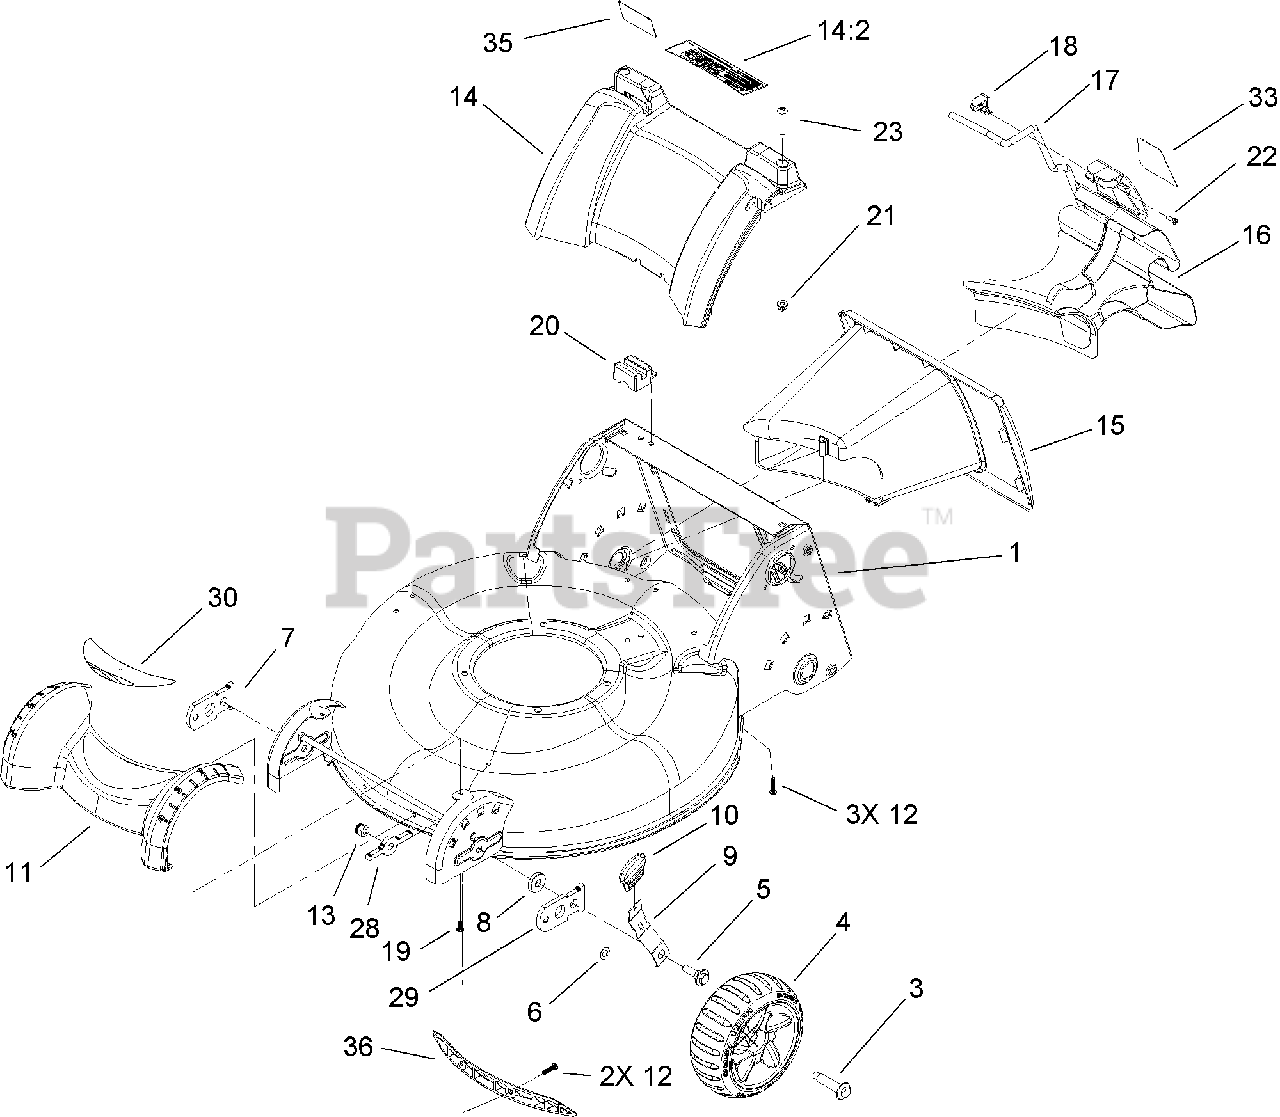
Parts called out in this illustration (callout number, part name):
1	HOUSING ASM
3	BOLT-SHOULDER
4	7 INCH FRONT WHEEL ASM
5	BOLT-SHOULDER
7	ARM-PIVOT, RH
9	ARM-SPRING
10	KNOB-LEVER, HOC
11	COVER-FRONT
12	SCREW-PLASTITE
13	NUT-LOCK, NI
14	COVER-REAR
14:2	DECAL-SAFETY
16	PLUG-CHUTE
17	LATCH-PLUG
18	RETAINER-LATCH
19	SCREW-PLASTITE
20	MODULE-SWITCH
21	NUT-CLIP
22	SCREW-PPH
23	SCREW-PTH
28	WASHER-SUPPORT, FRONT
29	ARM-PIVOT, LH
35	DECAL-BAG ATTACHMENT
36	INSERT-HOUSING
